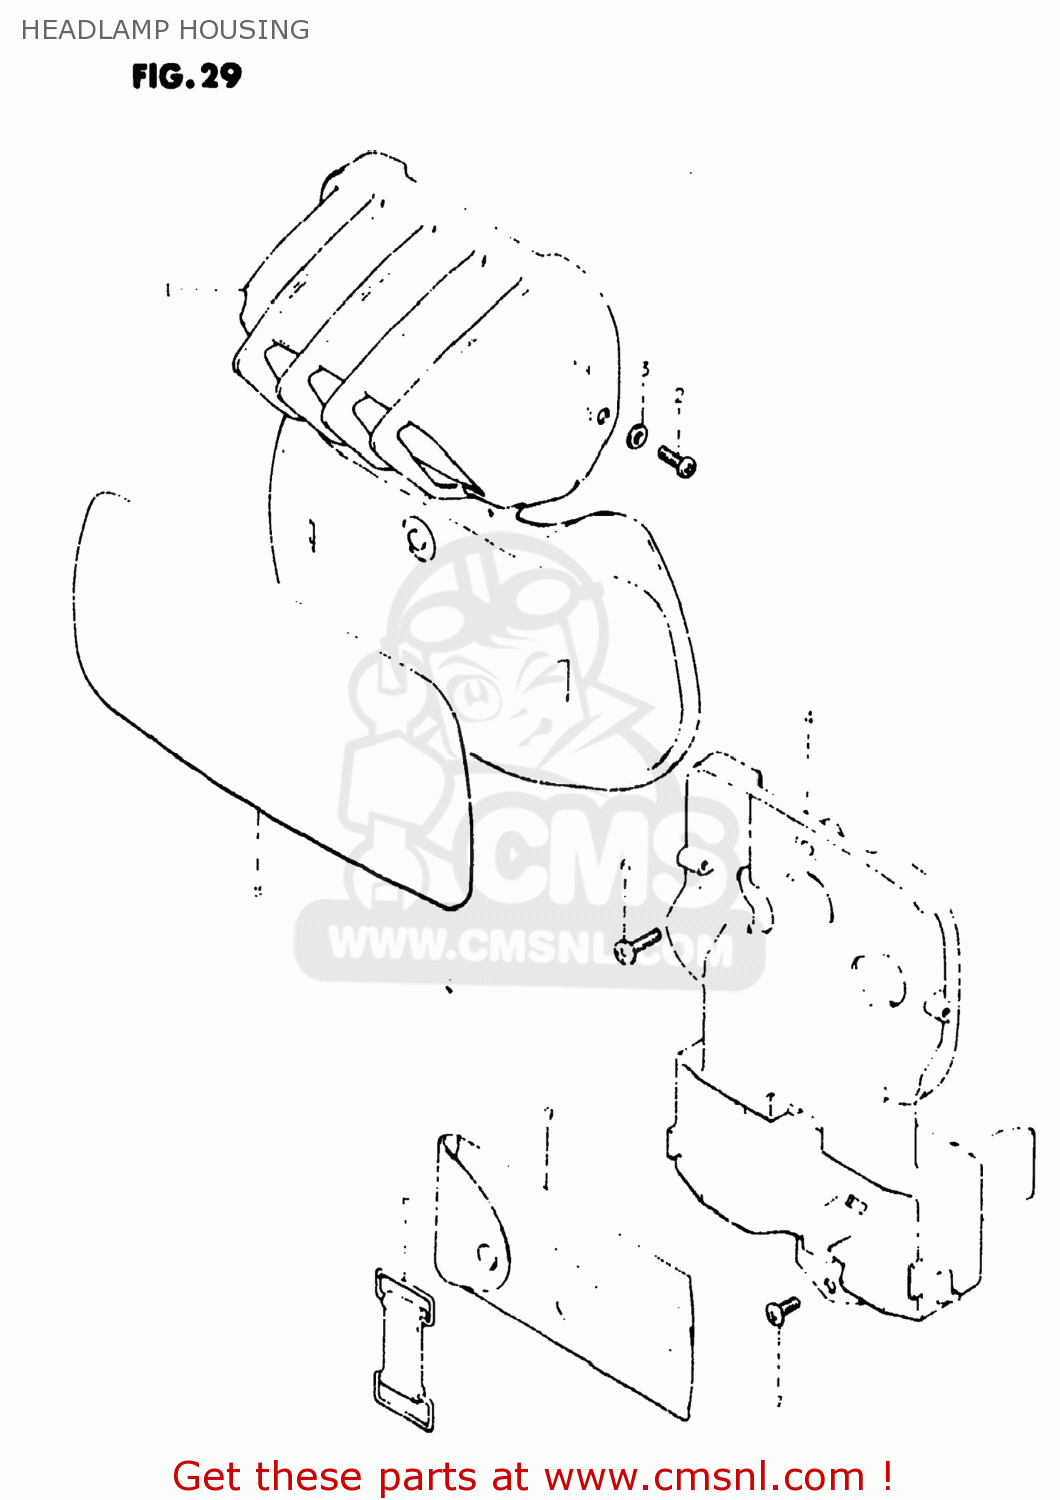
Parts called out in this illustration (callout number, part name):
1	HOUSING,HEADLAMP
2	TAPPING SCREW
3	WASHER
4	HOLDER,TOOL
5	BAND
6	SCREW
7	SCREW
8	EMBLEM,FRONT NUMBER PLATE
9	TOOL SET
